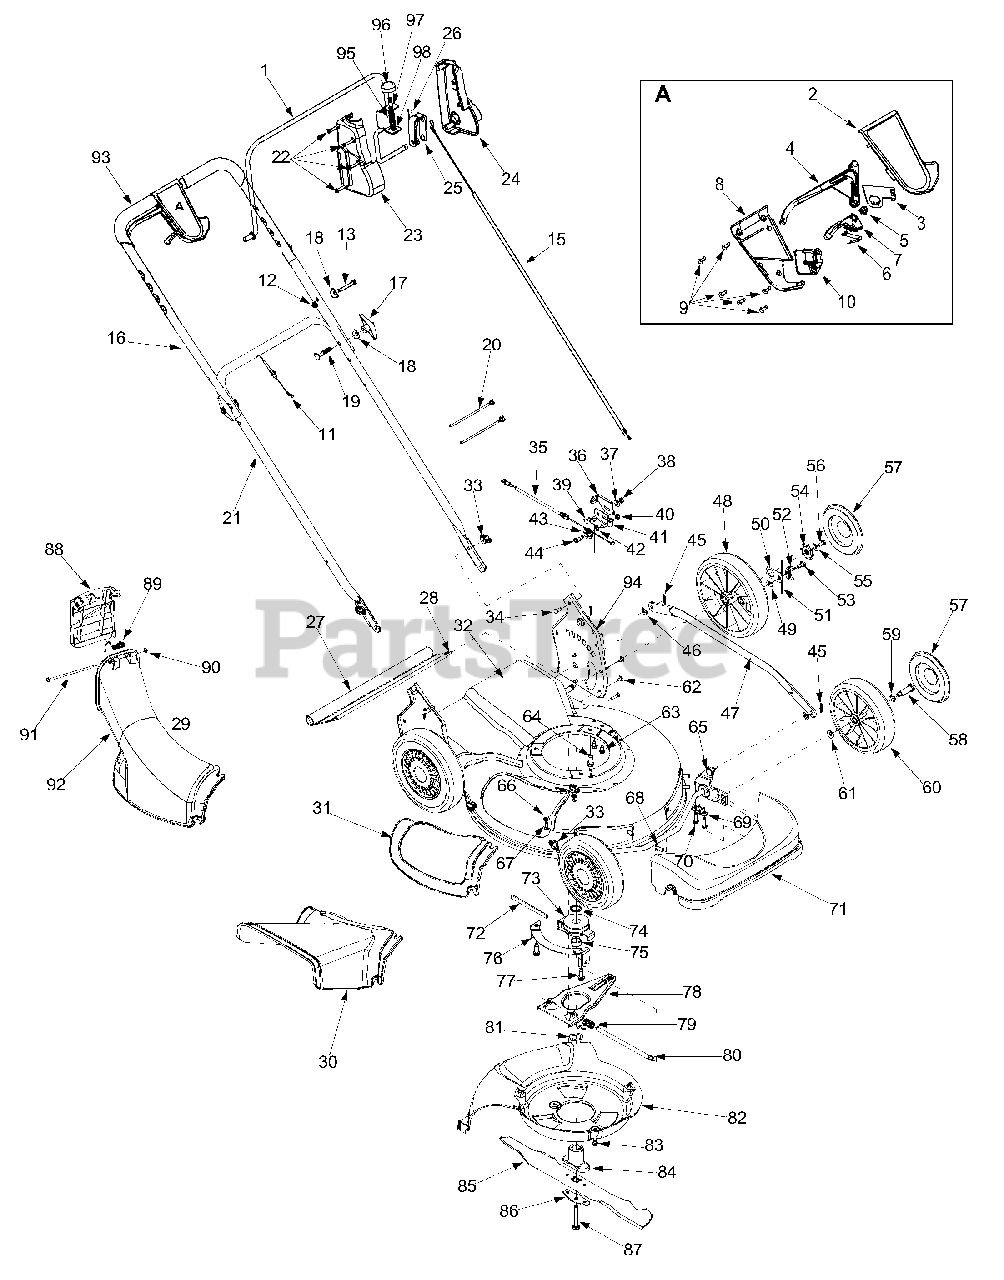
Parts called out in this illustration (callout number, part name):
2	Upper Control Handle
3	6 Spd. Rack Cable Bracket
4	Control Lever
5	Gear Insert
6	Shift Lever Spring
7	6 Speed Shift Lever
8	Lower Control Housing
9	C Sunk Tap Screw #10 x .75 Lg
10	Cable Mounting Cap
11	Drive Cable 51.0
12	Hex Lock Nut 1/4-20 Gr. 8
13	Hex Hd. Cap Screw 1/4-20 Gr. 5
15	Control Cable 58.25"
18	Saddle Washer .320 ID x .830 OD
19	Carriage Bolt 5/16-18 x 2.0
20	Cable Tie
22	Hi-Low Screw
23	Control Cover RH
24	Control Cover LH
26	Torsion Spring
27	Trail Shield
28	Trail Shield Wire
29	Chute Assembly
30	Side Discharge Chute
31	Mulch Cover
34	Carriage Bolt 1/4-20 x .75
35	6 Speed Cable
38	Hex Nut 1/4-20
39	Carriage Screw 1/4-20 x .50
40	Hex Nut 1/4-28
43	Roller Cable
44	Shoulder Screw .375 ID x 1/4-14
45	Cotter Pin
46	Bowed Washer
48	Wheel 9 x 2
49	Top Lock Tab Weld Nut 1/4-20
50	Ratchet Pawl Plate
51	Plastic Spring Ratchet
53	Shld Screw .340 ID x .285 OD
54	Wheel Rachet
55	Bell Washer .265 ID x .75 OD
56	Hex Cap Screw 1/4-20 x .620
57	Hubcap
58	Shoulder Screw .498 x 1.445
59	Wave Washer .510 ID x .750 OD
60	Wheel 8 x 2
61	Spring Washer .401 ID x .870 OD
62	Screw 1/4-14 x .500
63	Screw 1/4-14 x .625
64	Hex Washer Screw 3/8-16 x 1.0
66	Flat Washer .344 ID x .62 OD
67	Carriage Screw 1/4-20 x .75
68	Torx Screw
69	Block Bushing
70	Hex Washer Screw
71	Front Axle Cover
72	Belt 3/8 x 39.24
73	Pulley Assembly
74	Sleeve Spacer .88 ID x 1.13 OD
75	Sleeve Spacer .88 ID x 1.00 OD
77	Screw 3/8-18 x 1.0
80	Pivot Shaft
81	Wave Washer 1.38 ID x .88 OD
82	Baffle
83	Screw 1/4-20 x 3.75
84	Blade Adapter Kit
85	21" Mulching Blade
86	Blade Bell Support
87	Hex Bolt 3/8-24 x 2.5
88	Chute Door
89	Torsion Spring
91	Pivot Rod
92	Discharge Chute
93	Grip
98	Retention Spring
